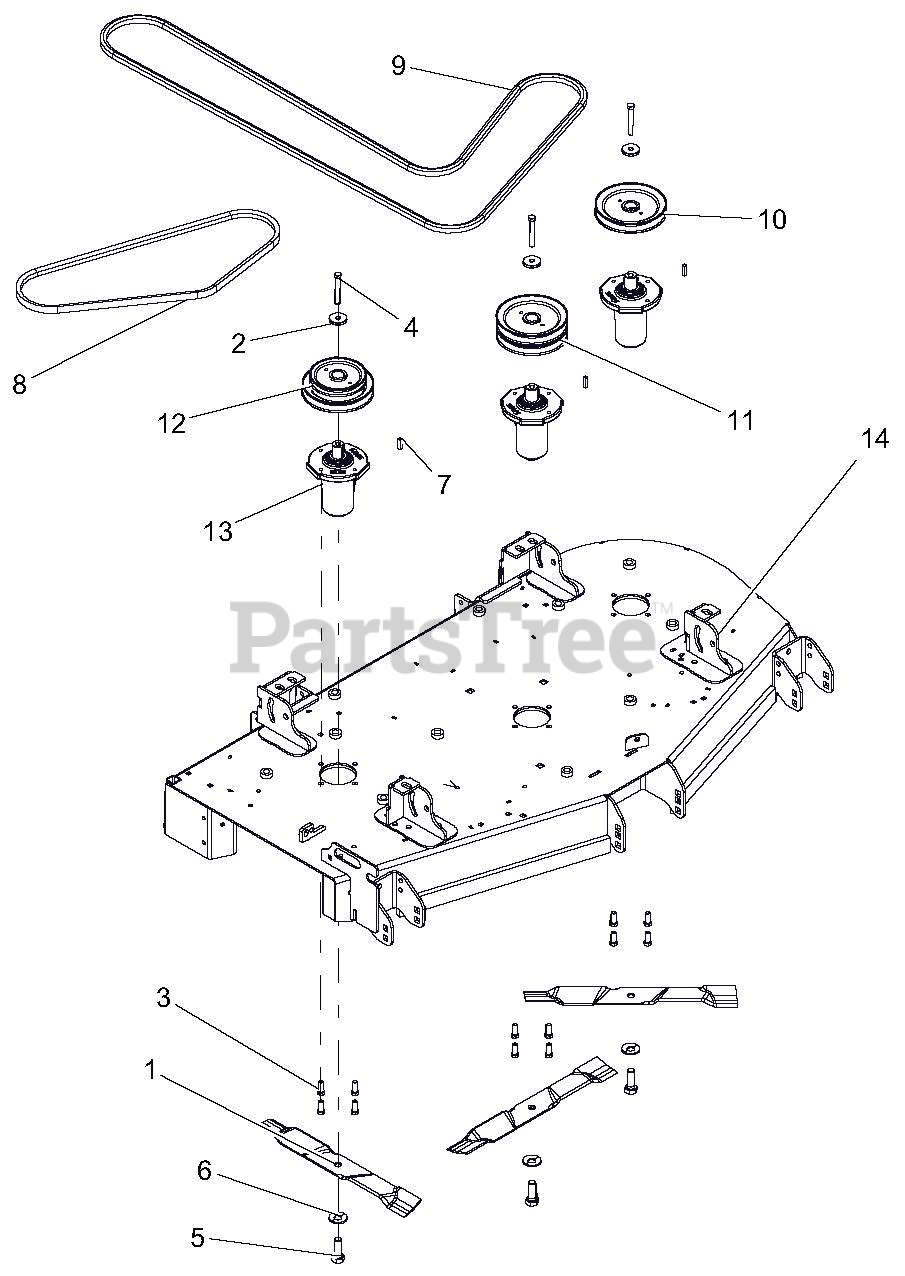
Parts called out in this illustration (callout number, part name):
1	BLADE, MULCH - 18.00"
2	RETAINER, SHEAVE SPINDLE
3	BLT-HEX .38-16X1.00 GR5 YWZC EP30
4	BLT-HEX .38-16X2.75 GR8 YWZC
5	BLT, HEX .62-18X1.75 GR8 YWZC
6	WSHR, BLVL .63X1.625X.14
7	KEY-SQ .250X.250X1.00 RC 40-50
8	BELT, B 56.00 RAW COGGED
9	BELT, BB 118.00 WRAPPED HEX
10	PULLEY, SINGLE -1" ID X 6.00" OD
11	PULLEY, DOUBLE -1" ID X 6.00" OD
12	PULLEY, DOUBLE -1" ID X 6.00" & 4.75" OD
13	SERVICE, ASM SPINDLE- DUCTILE
14	52" CE MOWER DECK W/SAFETY DECALS
